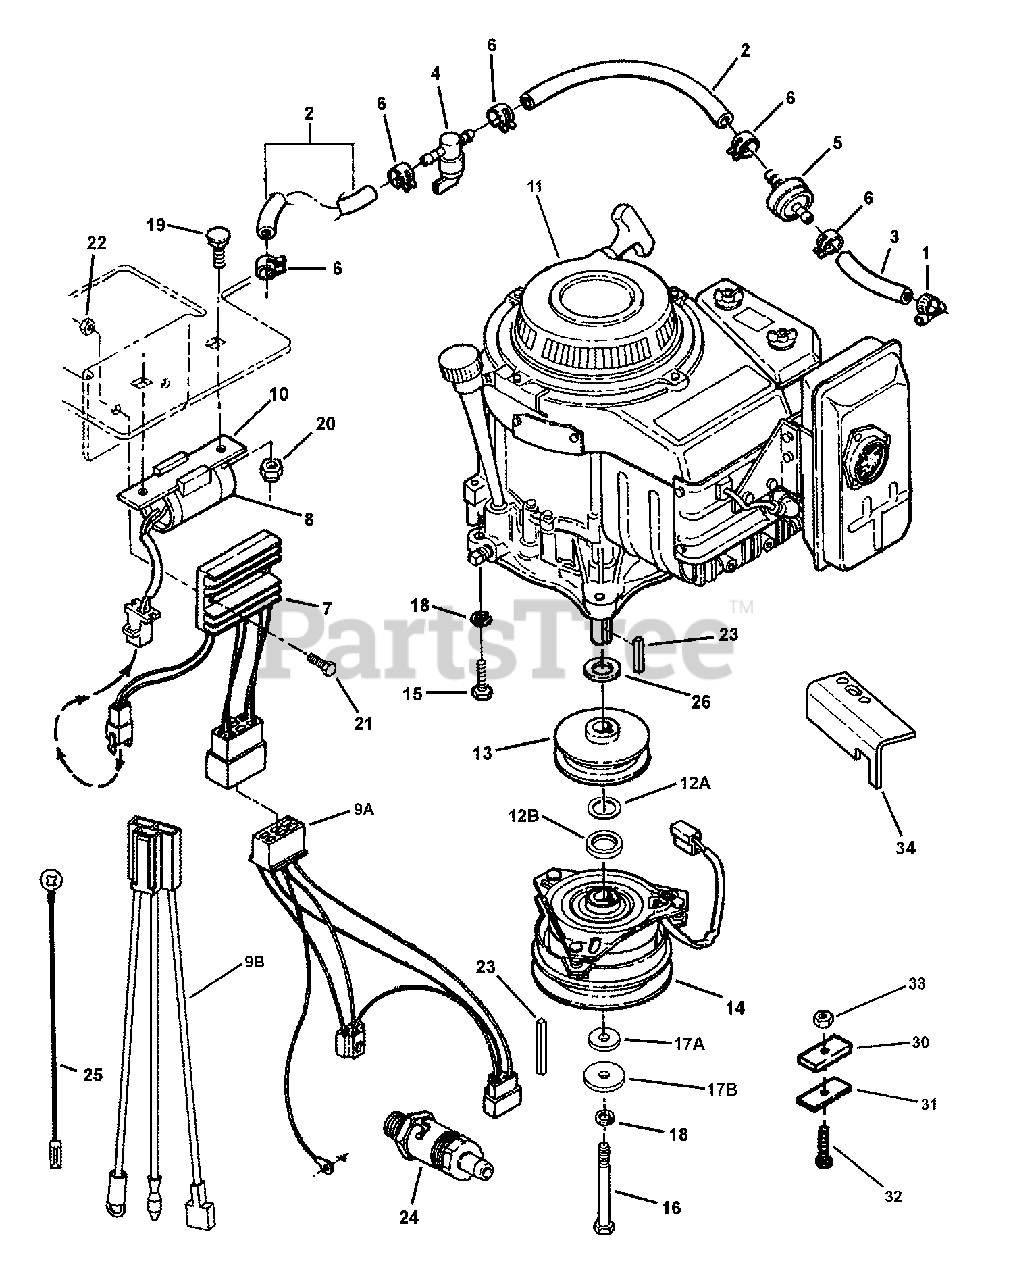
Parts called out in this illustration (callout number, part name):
1	CLAMP, Fuel Hose
2	LINE, Fuel, 1/4" I.D. x 1/2" O.D. x 8-1/2"
2	LINE, Fuel, 1/4" I.D. x 1/2" O.D. x 10"
3	LINE, Fuel, 1/4" I.D. x 1/2" O.D. x 3-1/2"
4	VALVE, Fuel
5	FILTER, In-Line
6	CLAMP, Fuel Hose
7	RECTIFIER/REGULATOR, Kawasaki
8	CAPACITOR, Kawasaki Engine
9A	HARNESS, Wiring Pigtail
9B	HARNESS, Wiring Pigtail
10	BRACKET, Capacitor
11	ENGINE, Kawasaki 12.5 HP
11	ENGINE, Kawasaki 13 HP
11	ENGINE, Kawasaki 14 HP
11	ENGINE, Kawasaki 15 HP "Express"
11	ENGINE, Kohler 15 HP
12A	BUSHING, 1" x 14 Ga Machine
12B	SPACER, Ogura Clutch
13	PULLEY, Engine
14	CLUTCH, Electric (Warner p/n 1-5215-14)
14	CLUTCH, Electric (Ogura p/n EXM3XR)
14	CLUTCH, Electric (Ogura model GT2.5 SN01)
15	BOLT, M8-1.25 X 25MM GD8.8
15	SCREW, 5/16-18 x 1-1/2" Hex Head Cap, GR 5
16	SCREW, M10-1.5 x 65 Hex Head Cap
16	BOLT, 7/16-20 X 3" GD5
16	SCREW, 7/16-20 x 2-1/2" Hex Head Cap, GR 5
17A	WASHER, .468 x 1.38 x .25 Flat
17B	SPACER, Clutch
18	WASHER, 7/16" Split Lock
18	WASHER, .32 x .58 x .08 Split Lock
19	BOLT, 5/16-18 x 1" Short Neck Carriage, GR 5
20	NUT, 5/16-18 HEX NYLON LOCK
21	SCREW, 1/4-20 x 1-1/4" Hex Head Cap
22	NUT, 1/4-20 HEX NYLON LOCK
23	KEY, 1/4" Square x .687
23	KEY, 1/4" Square w/Bevel
23	KEY, 1/4" Square x 2-1/2"
23	KEY, 1/4" Square x 2-1/4"
24	OIL VALVE ASSEMBLY
25	WIRE, Kohler Engine Ground
26	SPACER, Crankshaft
29	O-RING
30	BUMPER, Electric Clutch
31	WASHER, Rectangular Steel
32	BOLT, 5/16-18 X 1-1/4 GD5 YZ
33	NUT, 5/16-18 Hex Top Lock, GR B
34	BRACKET, Anti-Spin
